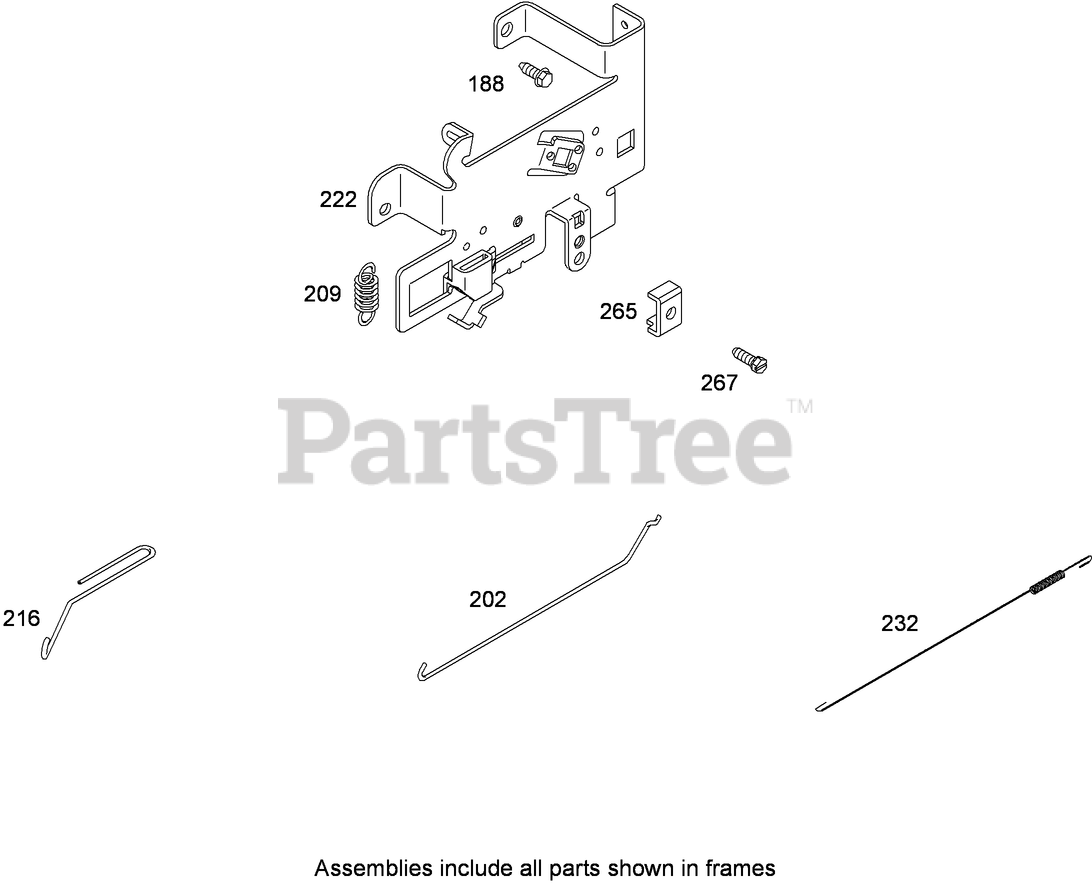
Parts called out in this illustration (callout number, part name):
188	Screw
202	Link-Governor, Mechanical
209	Spring-Governor
216	Link-Choke
222	Bracket-Control
232	Spring-Link, Governor
265	Clamp-Casing
267	Screw (Casing Clamp)
